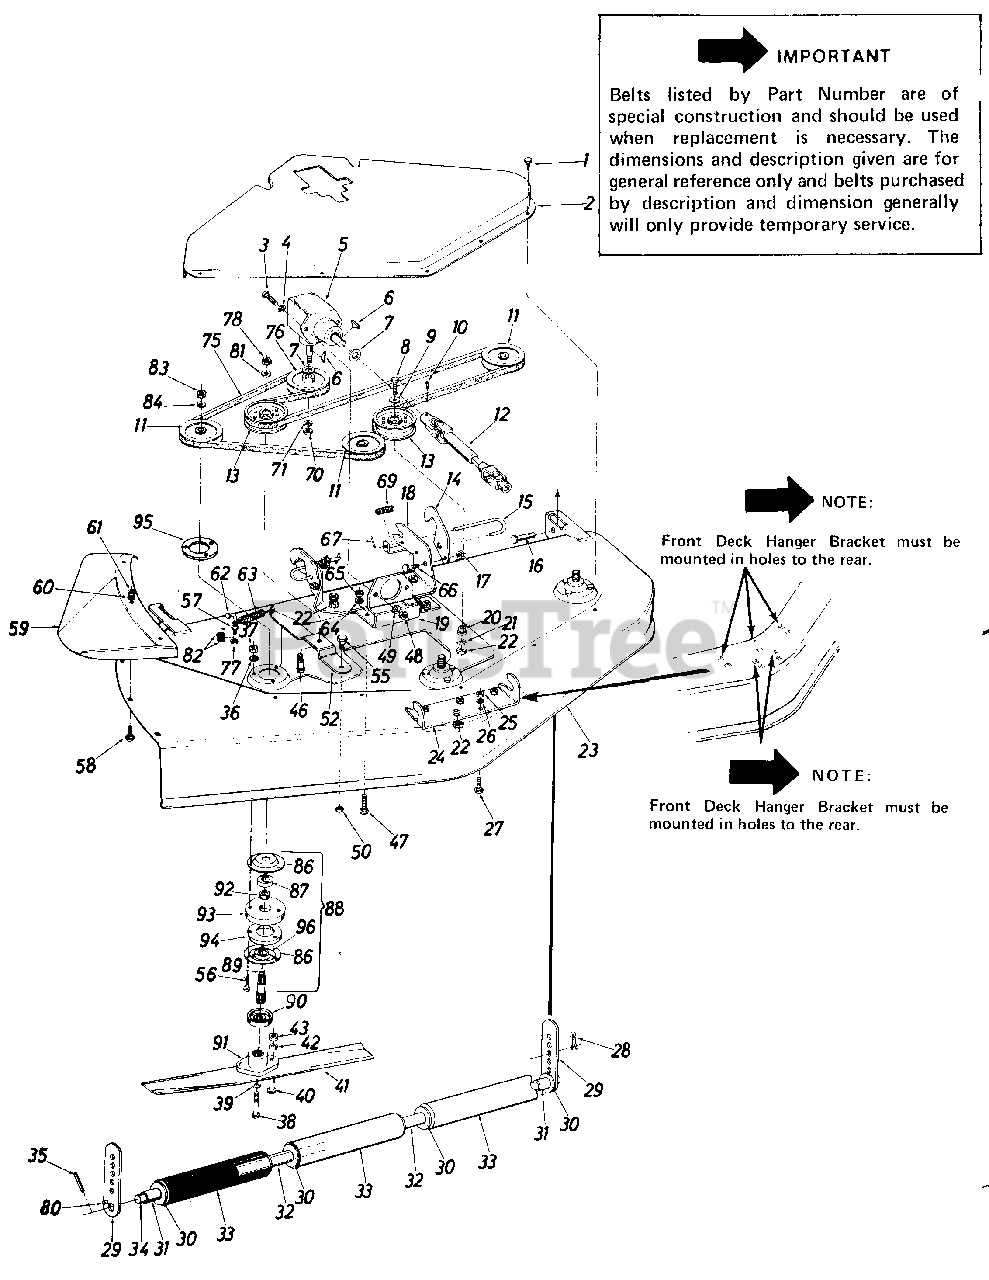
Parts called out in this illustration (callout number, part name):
1	Hex B Tap Scr. 1/4-20 x .38" Lg.
4	Ext. L-Wash. 3/8" Scr.*
5	Right Angle Drive
6	#9 Hi-Pro Key 3/16 x 3/4" Dia.
7	Fl-Wash. 29/32 I.D.
8	Hex Scr. 3/8-16 x 2.25" Lg.*
9	Fl-Wash. 3/8" I.D.
10	Sq. Hd. Set Scr. 3/8-16 x .50" Lg. Cup
11	Deck Pulley
12	Universal Drive Shaft Ass'y.
13	Deck Idler Pulley
14	Hanger Lock
15	Release Pin
16	Clevis Pin .500 Dia.
17	Hex Cent. L-Nut5/16-18 Thd.
21	L-Wash. 3/8" Scr.*
22	Hex Nut 3/8-16" Thd.*
23	Deck Ass'y. 50"
26	L-Wash. 5/16" Scr.*
27	Carriage Bolt 5/16-18 x 1.00" Lg. *
28	Internal Cotter Pin
30	Fl-Wash. .75 I.D. x 1.5 O.D.
31	Spacer .758 I.D. x 1.25 O.D. x .530
34	Roller Shaft
35	Roll Pin 3/16 x 1.25
36	L-Wash. 5/16" Scr.*
37	Hex Cent. L-Nut 5/16-24 Thd.
38	Hex Scr. 3/8-24 x .75" Lg. Thd. Rolling
39	L-Wash. 3/8" Scr. H.D.
40	Hex Scr. 5/16-24 x 1.00" Lg.
41	Blade 17"
42	L-Wash. 5/16" Scr.*
43	HexCent. L-Nut5/16-24Thd.
46	Hex Scr. 5/8-18 x 1.31 " Lg.
47	Carriage Bolt 5/16-18 x .75"
48	Hex Nut 3/8-16 Thd.*
49	L-Wash. 3/8" Scr.*
50	Hex Cent. L-Nut 7/16-14
56	Hex Scr. 5/16-24 x 1.50" Lg.(Grade 5)
57	Hex Nut 1/4-20 Thd . *
58	Carriage Bolt 5/16-18 x .75 Lg.*
60	L-Wash. 5/16" Scr.*
61	Hex Nut 5/16-18Thd.*
62	Hook Bolt
63	Extension Spring
64	L-Wash. 5/16" Scr.
65	Hex Nut 5/16-18 Thd.*
66	Shld. Scr.
67	Roll Pin 1/8" Dia.
69	Compression Spring
70	Hex Cent. L-Nut5/8-18Thd.
71	L-Wash. 5/8" Scr.*
75	"V"-Belt
76	Drive Pulley
77	Hex Cent. L-Nut 1/4-20 Thd.
78	Hex Cent. L-Jam Nut 5/8-18 Thd.
80	Spring Pin Spiral 1/4" Dia. 1.00" Lg.
81	Fl-Wash..62" I.D.
82	Ext. L-Wash. 1/4" Scr.*
83	Hex Jam Nut 5/8-18 Thd.
84	L-Wash. 5/8" I.D.*
86	Bearing Housing
87	Ball Bearing
88	Deck Spindle Ass'y.
89	Spindle
90	Bearing Shield
91	Blade Adapter
92	Spacer
93	Spindle Spacer Plate
94	Reinforcement Plate
95	Spindle Reinforcement Plate
96	Open Bearing Housing
